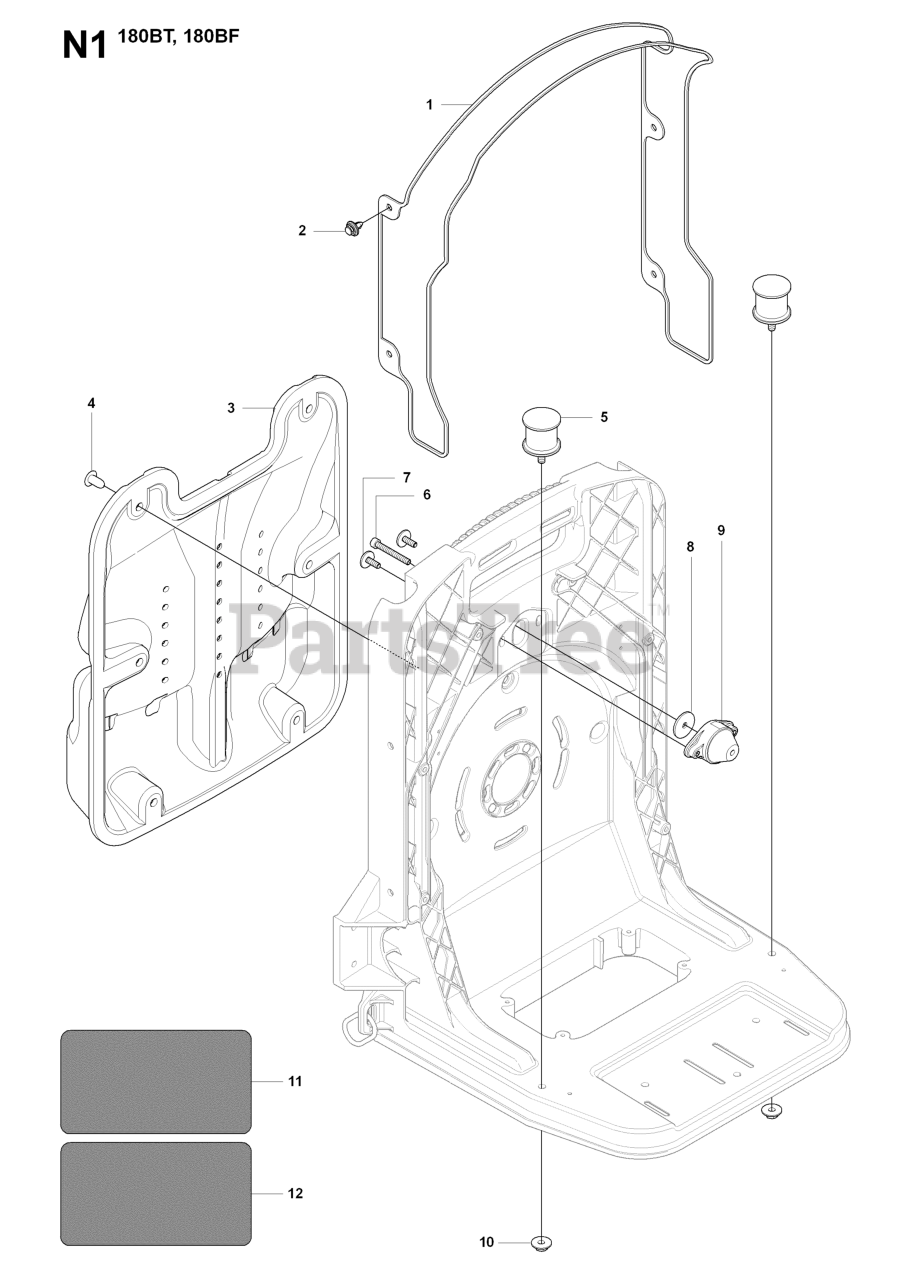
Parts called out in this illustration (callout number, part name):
2	CLIP
4	CLIP
5	DAMPER
6	CLIP
7	BOLT
8	WASHER
9	DAMPER
10	NUT (M6)
